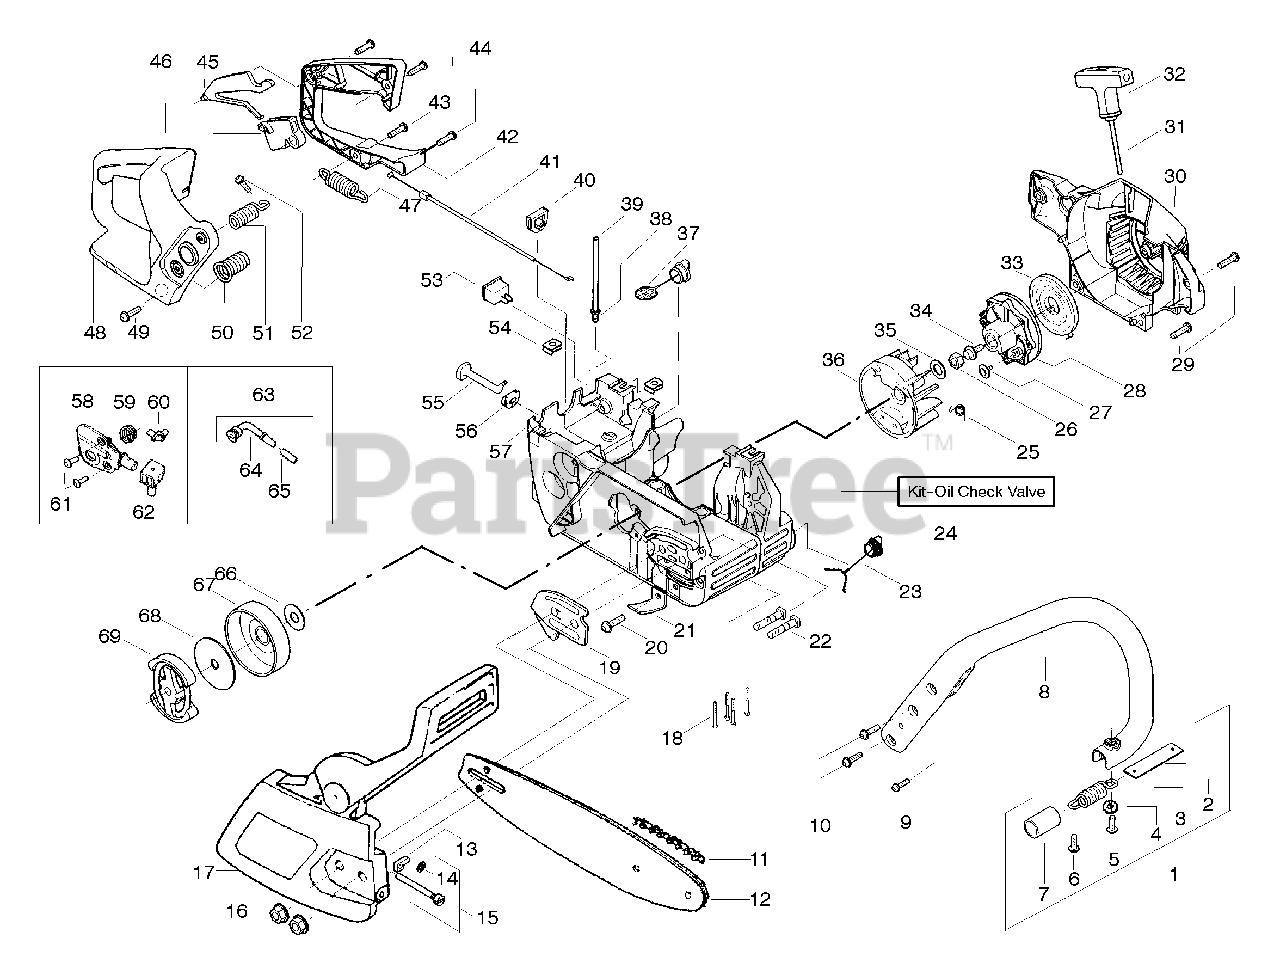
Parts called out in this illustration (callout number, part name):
1	Assy.-Isolator
2	Limiter Strap
3	Spring-Isolator
7	Sleeve-AV Spring
8	Front Handle
11	Chain-18"
13	Pin Bar Adjust
14	Retainer-Bar Adjust
15	Kit-Bar Adj.
16	Nut-Bar Mounting
17	Assy-Chain Brake
19	Plate-Bar Mounting
21	Chain Catcher
22	Bolt-Bar
23	Oil Cap Ass'y.
24	Kit-Oil Check Valve
25	Spring-Starter Dog
26	Nut-Flywheel
28	Starter Pulley
30	Fan Housing
31	Kit-Rope
32	Starter Handle
33	Recoil Spring
35	Washer-Flywheel
36	Assy-Flywheel
37	Fuel Cap Ass'y.
38	Fitting-fuel line
39	Kit-Fuel line (large)
40	Grommet-Cable
41	Cable-Throttle
42	Cover-Rear Handle
45	Throttle Lockout
46	Trigger-Throttle
47	Spring-Isolator
48	Handle-Rear
49	Screw
50	Assy. Isolator-lower
51	Kit-Isolator (Upper)
53	Kit-Switch
54	Nut-"U"-Type
55	Knob-Choke
56	Grommet-Knob
57	Assy-Chassis
58	Kit-Oil Pump
59	Gear-Worm Spring
60	Elbow-Oil Pickup
62	Seal Block
63	Assy-Oil Pick-up
64	Pick-up Oiler
65	Oil Filter
66	Washer-Thrust
67	Assy.-Clutch Drum w/bearing
68	Washer-Clutch
69	Assy. Clutch
